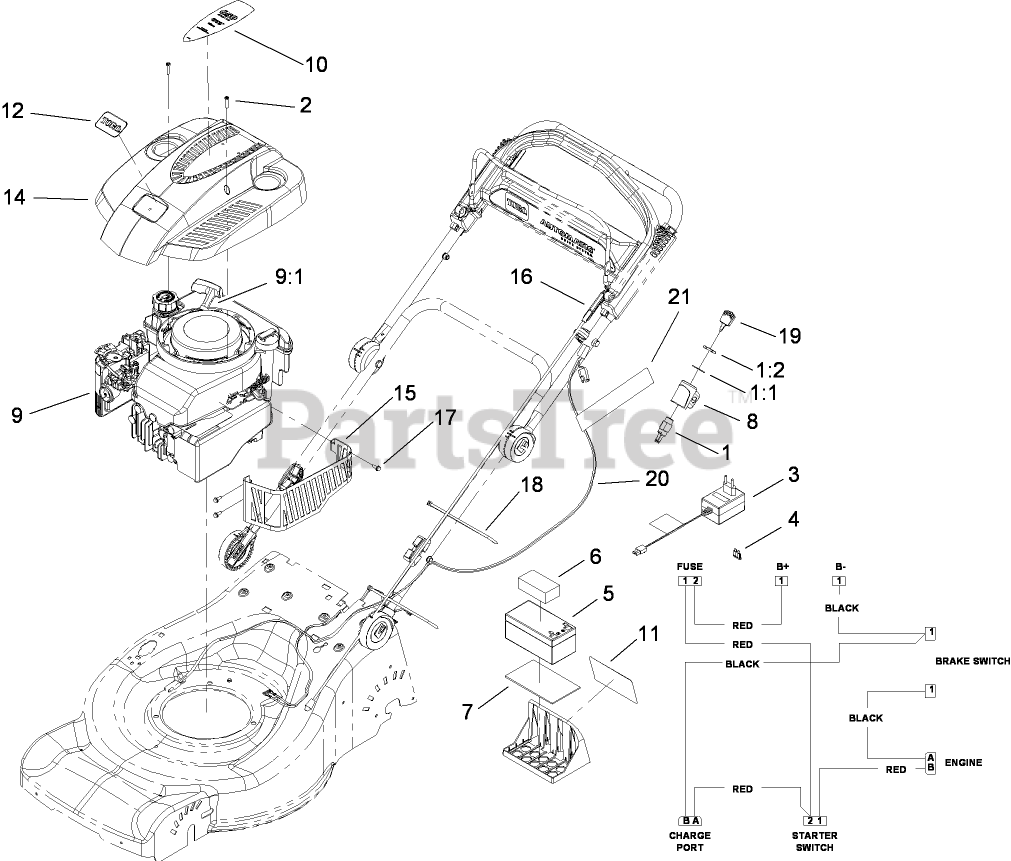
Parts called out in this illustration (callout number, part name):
1	STARTER SWITCH ASM
1:1	WASHER-LOCK
1:2	NUT-HH
2	SCREW-PPH
3	CHARGER-EUROPEAN, 12V DC
4	FUSE-40 AMP
5	BATTERY-WET
6	FOAM-BATTERY, TOP
7	FOAM-BATTERY
8	MOUNT-SWITCH
9	Loose Parts Package
9:1	STOP-ROPE
11	DECAL-FUSE
12	DECAL-TORO
14	SHROUD-ENGINE
15	SHIELD-MUFFLER
16	CABLE-BRAKE
17	SCREW-TAPTITE
18	TIE-CABLE
20	HARNESS-WIRING
21	DECAL-WARNING
